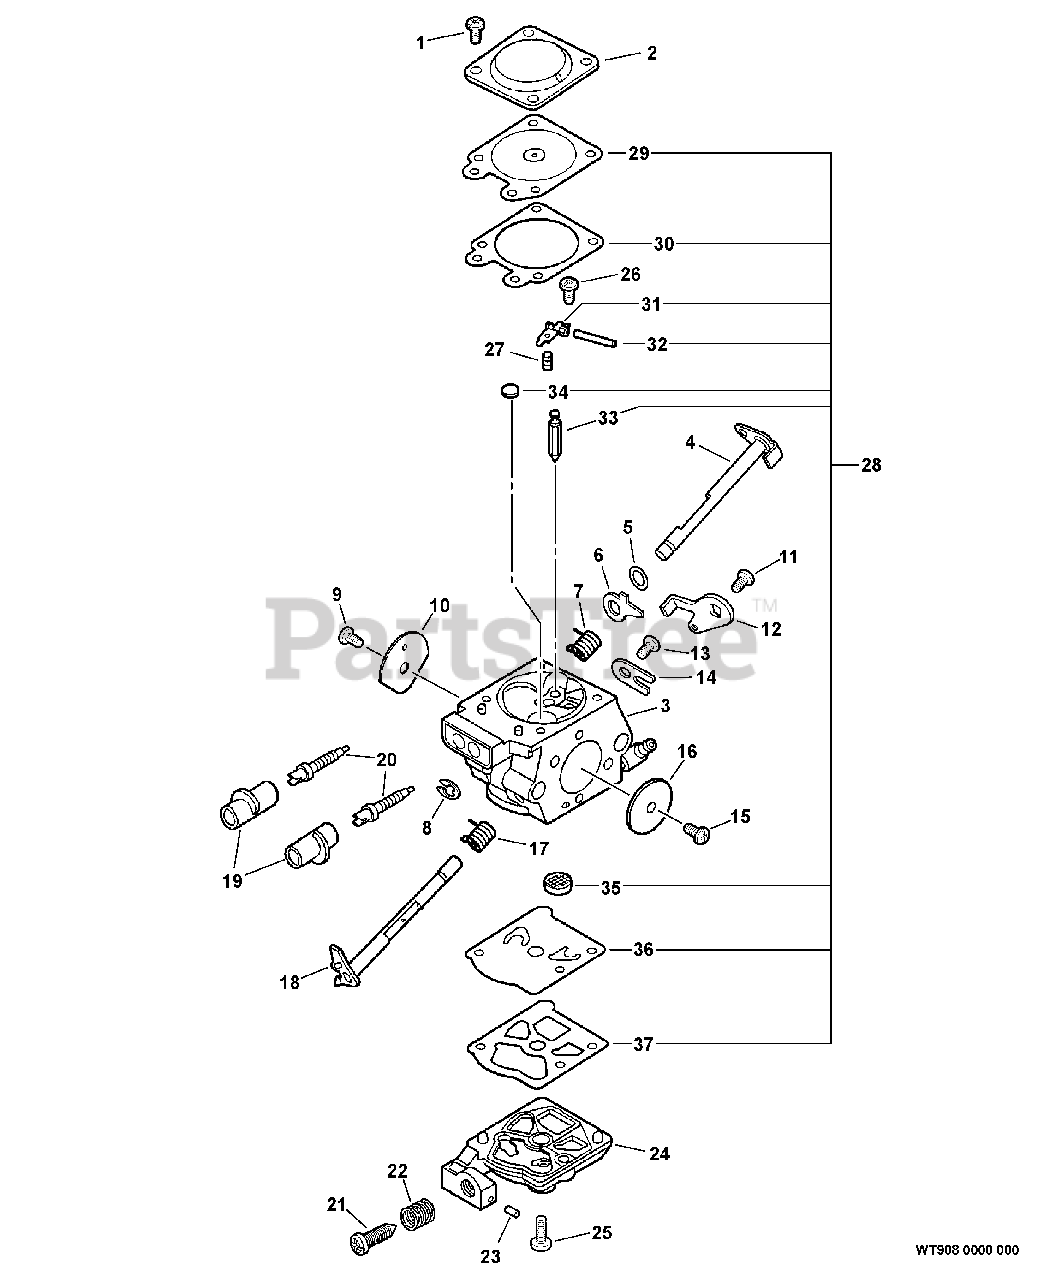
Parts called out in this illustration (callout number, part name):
2	COVER, METERING
3	BODY, CARBURETOR
4	SHAFT, CHOKE
6	LEVER, CHOKE
7	SPRING, CHOKE RETURN
8	RING, RETAINING
10	VALVE, CHOKE
12	LEVER, THROTTLE
14	CLIP, THROTTLE SHAFT
16	VALVE, THROTTLE
17	SPRING, THROTTLE RETURN
18	SHAFT, THROTTLE
19	CAP, LIMITER
20	NEEDLE - MIXTURE
21	SCREW, IDLE ADJUST
22	SPRING, IDLE ADJUST
24	COVER, PUMP
25	SCREW, PUMP COVER
26	SCREW, METERING LEVER PIN
27	SPRING, METERING LEVER
28	REPAIR KIT
29	DIAPHRAGM, METERING
30	GASKET, DIAPHRAGM
31	LEVER, METERING
32	PIN, METERING LEVER
33	VALVE, INLET NEEDLE
34	PLUG, WELCH
35	STRAINER
36	DIAPHRAGM, PUMP
37	GASKET, PUMP
